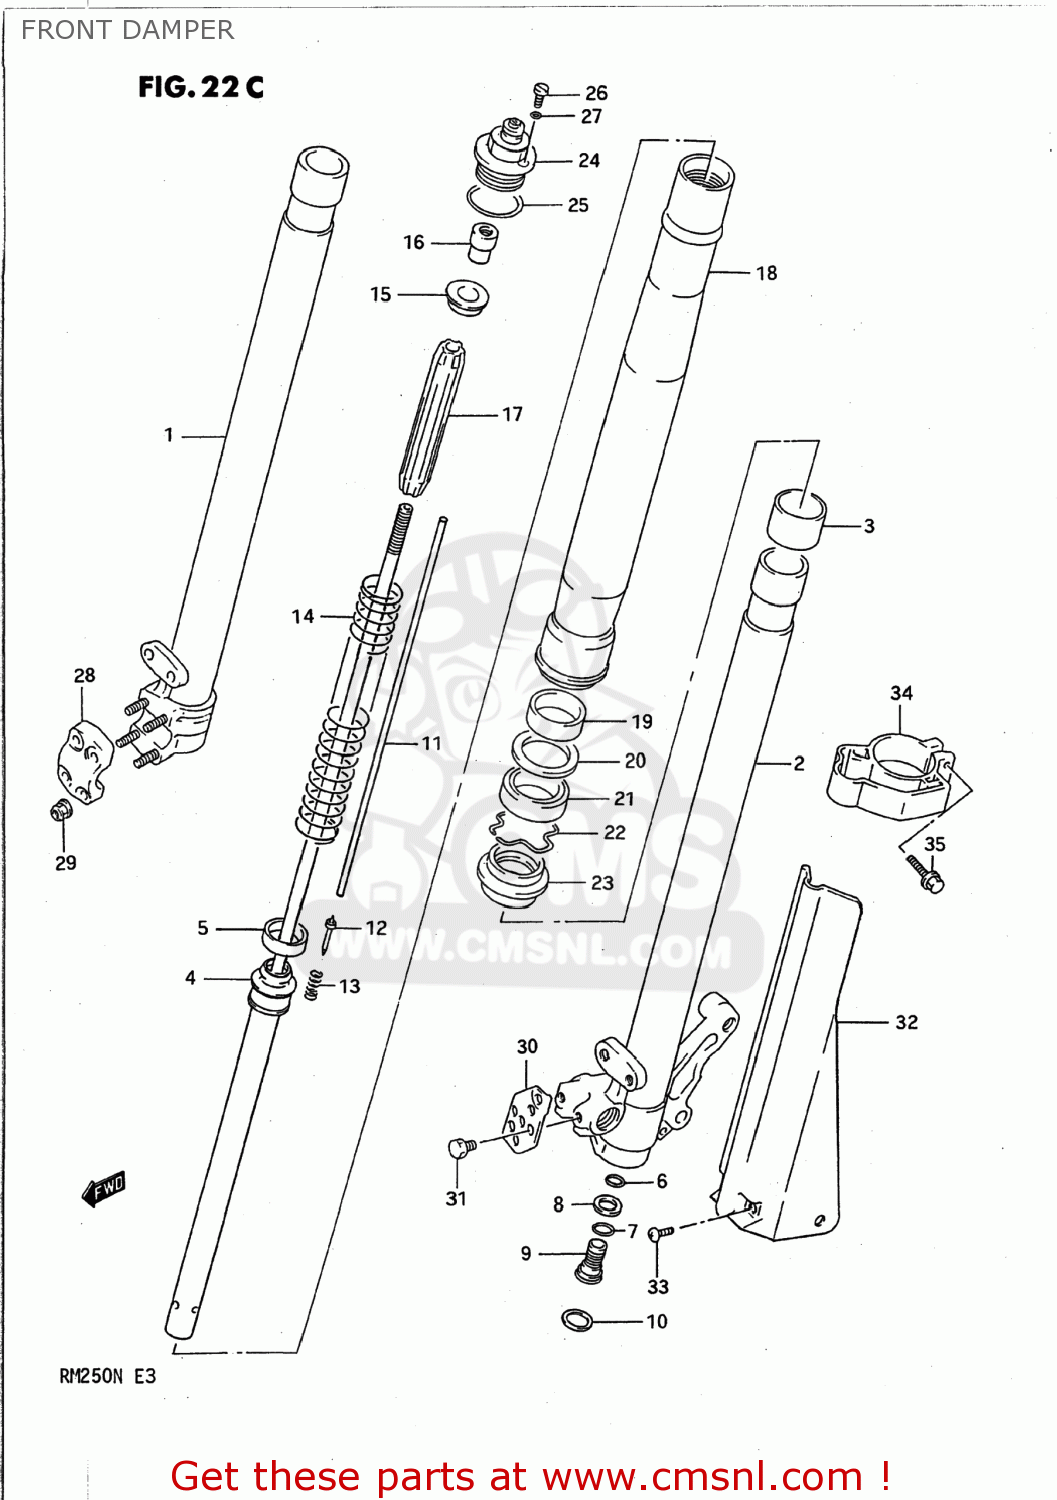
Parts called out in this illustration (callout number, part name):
1	TUBE,INNER,R
2	TUBE,INNER,LEFT
3	BUSH,SLIDE
4	DAMPER
5	RING,PISTON
6	O RING,CTR BOLT UPR
7	O RING,CTR BOLT
8	GASKET (NAS)
9	BOLT,CENTER
10	RING,CTR BOLT STOPPER
11	ROD,PUSH
12	NEEDLE
13	SPRING,PUSH RO
14	SPRING,MAIN
15	GUIDE,SPRING
16	NUT,ROD
17	SEAT,SPRING UPR
18	TUBE,OUTER
19	BUSH,GUIDE
20	SPACER,SEAL
21	OIL SEAL,FRONT FORK
22	RING,OIL SEAL STOPPER
23	SEAL,DUST
24	BOLT,FORK
25	O RING
26	BOLT,PLUG
27	O RING, PLUG
28	HOLDER,AXLE,R
29	NUT
30	GUIDE,HOSE,L
31	BOLT, HOSE GUIDE
32	PROTECTOR,FORK,LEFT
33	BOLT,PROTECTOR(6X10)
34	GUIDE,FORK PROTECTOR
35	BOLT,PROTECTOR GUIDE,6
